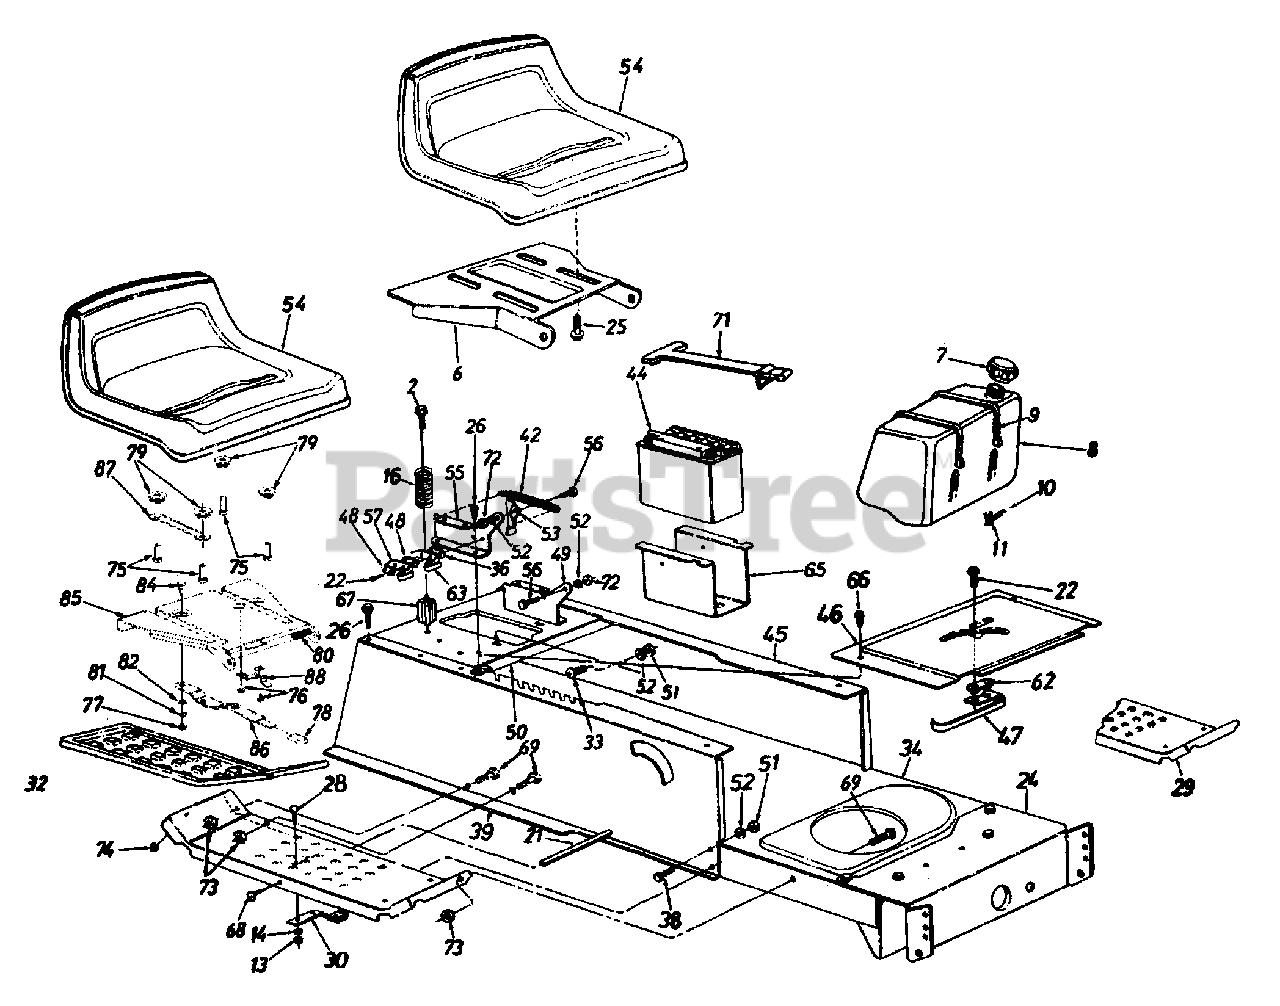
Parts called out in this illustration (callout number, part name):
2	Hex Tap Scr. 5/16-18 x 3.25"
7	Fuel Cap
8	Fuel Tank (1.5 Gal)
9	Tie Strap
10	Fuel Line
11	Hose Clamp
13	Hex Nut 1/4-20 Thd.
14	L-Wash. 1/4" I.D.
16	Compression Spring
21	Running Board Rod
22	Hex AB-Tap Scr. #8 x .50" Lg.
25	Hex Tap Scr. 3/8-16 x .62" Lg.
26	Hex Wash. Hd. AB-Tap Scr. 5/16 x .75"
28	Carriage Bolt 1/4-20 x .62"
32	Rubber Foot Pad - L.H.
36	Insulator Boss Plate
38	Hex Bolt 5/16-18 x .75" Lg.
44	12-V Battery
48	Insulator Plate
52	L-Wash. 5/16" I.D.
53	Seat Lift Brkt.
54	Seat 10-5/8" High
56	Shld. Bolt .437" Dia. x .268"
57	Spring Switch (Seat - Outer)
63	Safety Switch (Seat - Inner)
66	Truss Mach. B-Tap Scr.#10 x.5" Lg.
67	Spring Spacer
68	Truss Mach. Scr. 5/16-18 x .75"
69	Hex Bolt 5/16-18 x .75" Lg.
71	Battery Retainer Strap
72	Hex Nut 5/16-18 Thd.
73	Hex Sems Nut 5/16-18 Thd.
74	Hex Sems Nut 1/4-20 Thd.
75	Shoulder Screw 3/8-16 x.5
76	Hex Wash. B-Tap Scr. #10-16 x .38"
77	Hex Flanged L-Nut 1/4-20 Thd.
78	Seat Adjustable Grip
79	Spacer
80	Compression Spring 1.5" Lg.
81	Spring Wash. .265" I.D. x.56" O.D.
82	Fl-Wash. .344" I.D. x.62" O.D.
84	Shld. Bolt .34" x 1/4 -20 Thd.
87	Seat Selector
88	Seat Stop
